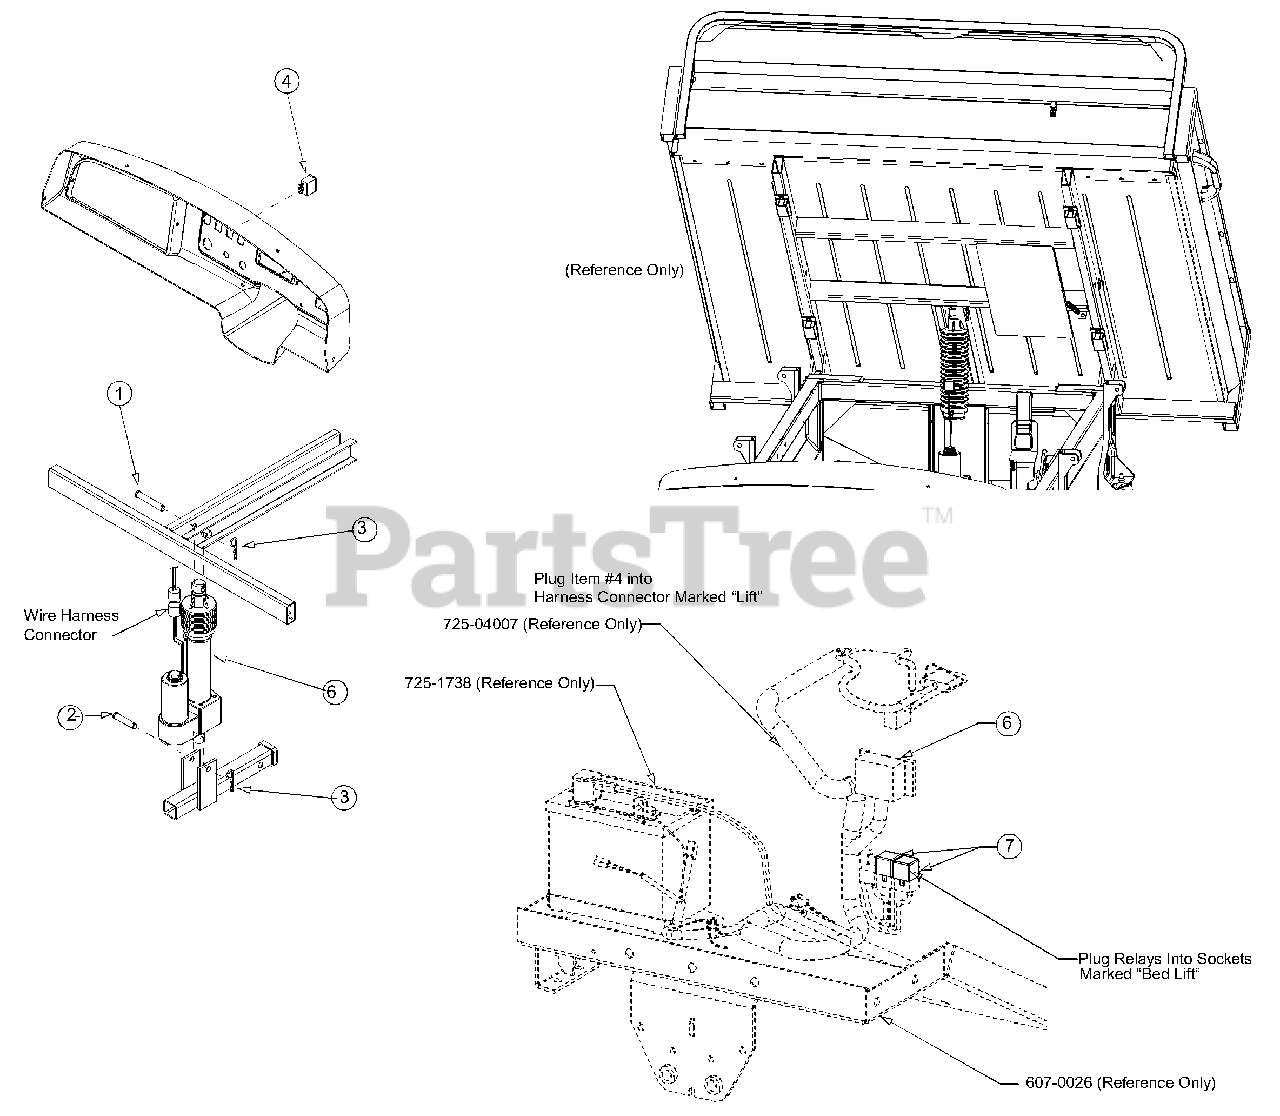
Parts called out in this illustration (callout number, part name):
1	Clevis Pin 3.0"
2	Clevis Pin 2.25"
3	Internal Cotter Pin
4	Cargo Box Switch
5	Actuator, Electric Bed Lift
6	Fuse 30 Amp
7	Relay 12V 40A (2)
